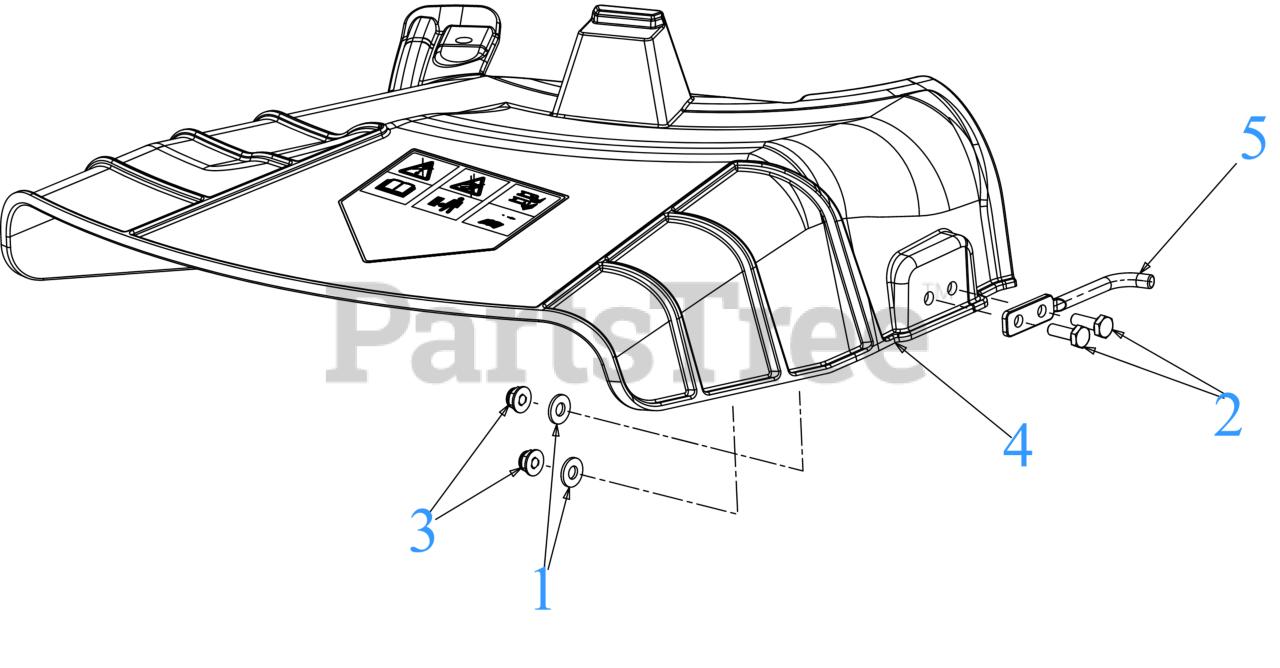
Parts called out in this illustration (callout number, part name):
1	BLADE GUARD MOUNTING HARDWARE
2	SCREW 1/4-20X.75 GR5
3	FLANGE LOCK NUT
4	36" DISCHARGE CHUTE
5	36" CHUTE SUPPORT ROD
